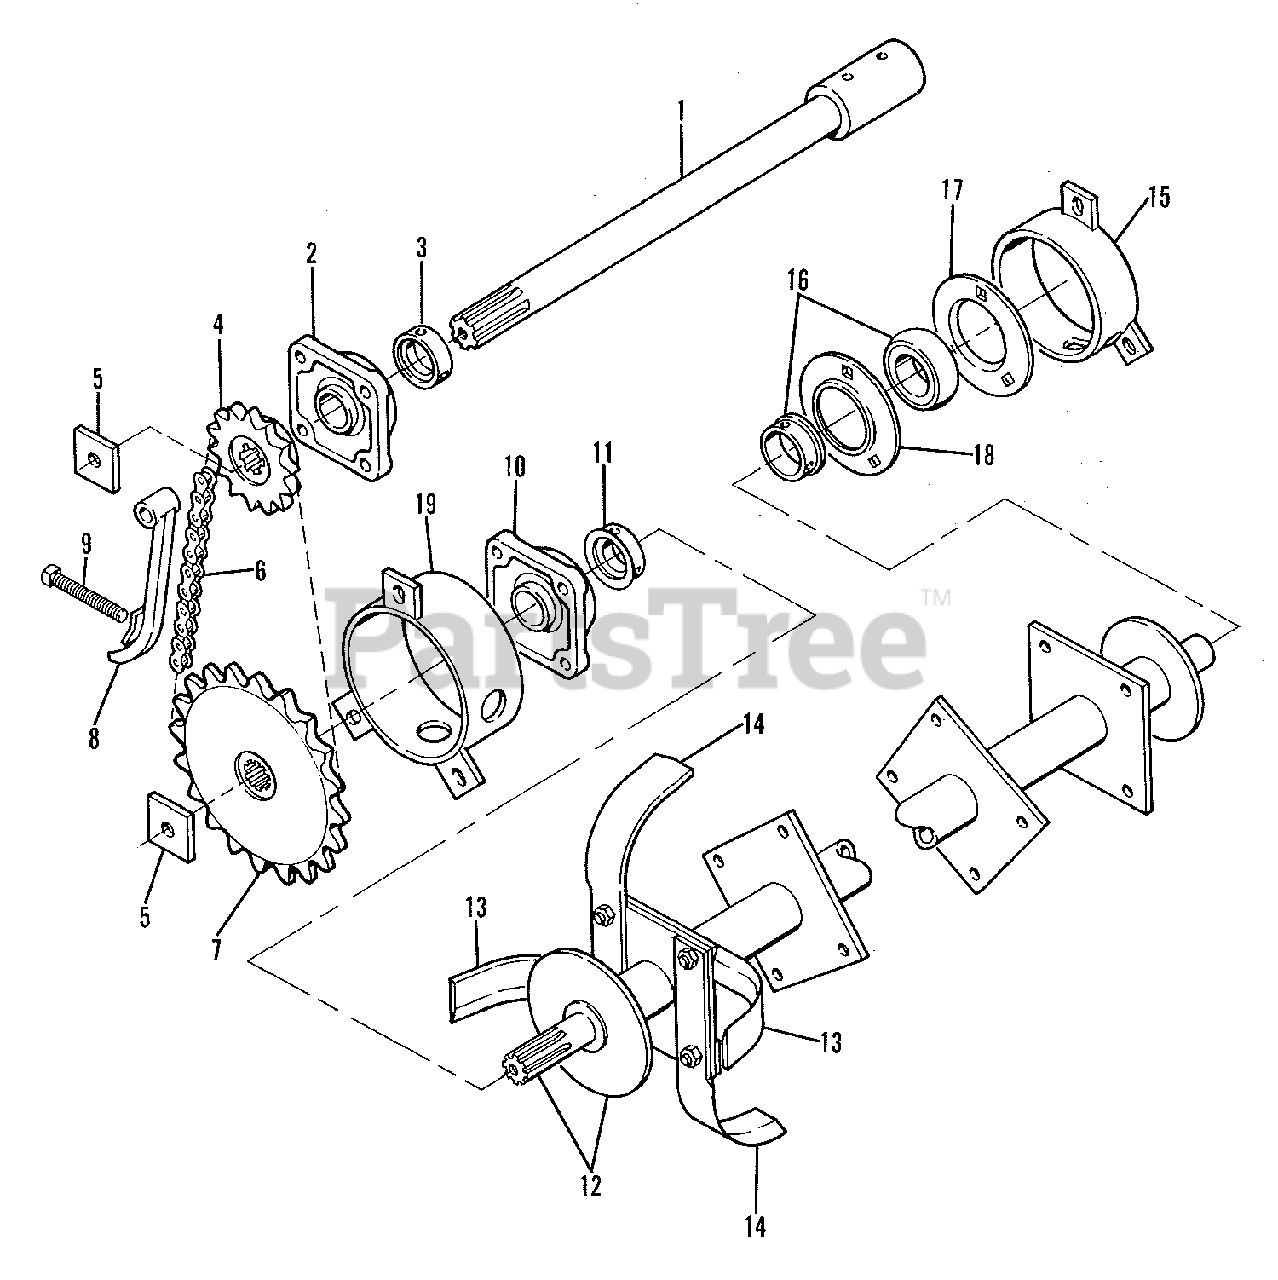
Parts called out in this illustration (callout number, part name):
1	KEY, Square, 3/8 x 2
1	SETSCREW, Square Head, Cup Point, 3/8NC x 3/4
1	NUT, Jam, 3/8NC
2	BEARING ASSEMBLY, Flange, 1-3/8
3	COLLAR, Bearing, 1-3/8
3	SETSCREW, Socket Head, Cup Point, 5/16NF x 3/8
4	SPROCKET, Upper (13T)
5	RETAINER, Sprocket
5	CAPSCREW, 3/8NC x 1
5	CAPSCREW, Nylok Insert, 3/8NC x 1
5	LOCKWASHER, 3/8
6	CHAIN ASSEMBLY, Drive (45 Link)
6	LINK, Connecting
6	LINK, Offset
7	SPROCKET, Lower (20T)
8	SLIDE, Chain
9	SCREW, Adjusting
9	NUT, Lock, 5/8NC
10	BEARING ASSEMBLY, Flange, 1-1/2
11	COLLAR, Bearing, 1-1/2
12	SHAFT ASSEMBLY, Rotor
13	BLADE, L.H.
13	BOLT, Blade
14	BLADE, R.H.
14	BOLT, Blade
15	COVER ASSEMBLY, Anti-Trash
15	CAPSCREW, 3/8NC x 1
15	NUT, Lock, 3/8NC
16	BEARING, Support
16	COLLAR, Locking
16	SETSCREW, Socket Head, Cup Point, 5/16NC x 1/2
17	HOUSING, Bearing (w/Lube Fitting)
17	BOLT, Carriage, 3/8NC x 7/8
17	NUT, Lock, 3/8NC
18	HOUSING, Bearing (w/o Lube Fitting)
19	COVER ASSEMBLY, Anti-Trash, L.H.
19	CAPSCREW, 3/8NC x 1
19	NUT, Lock, 3/8NC
